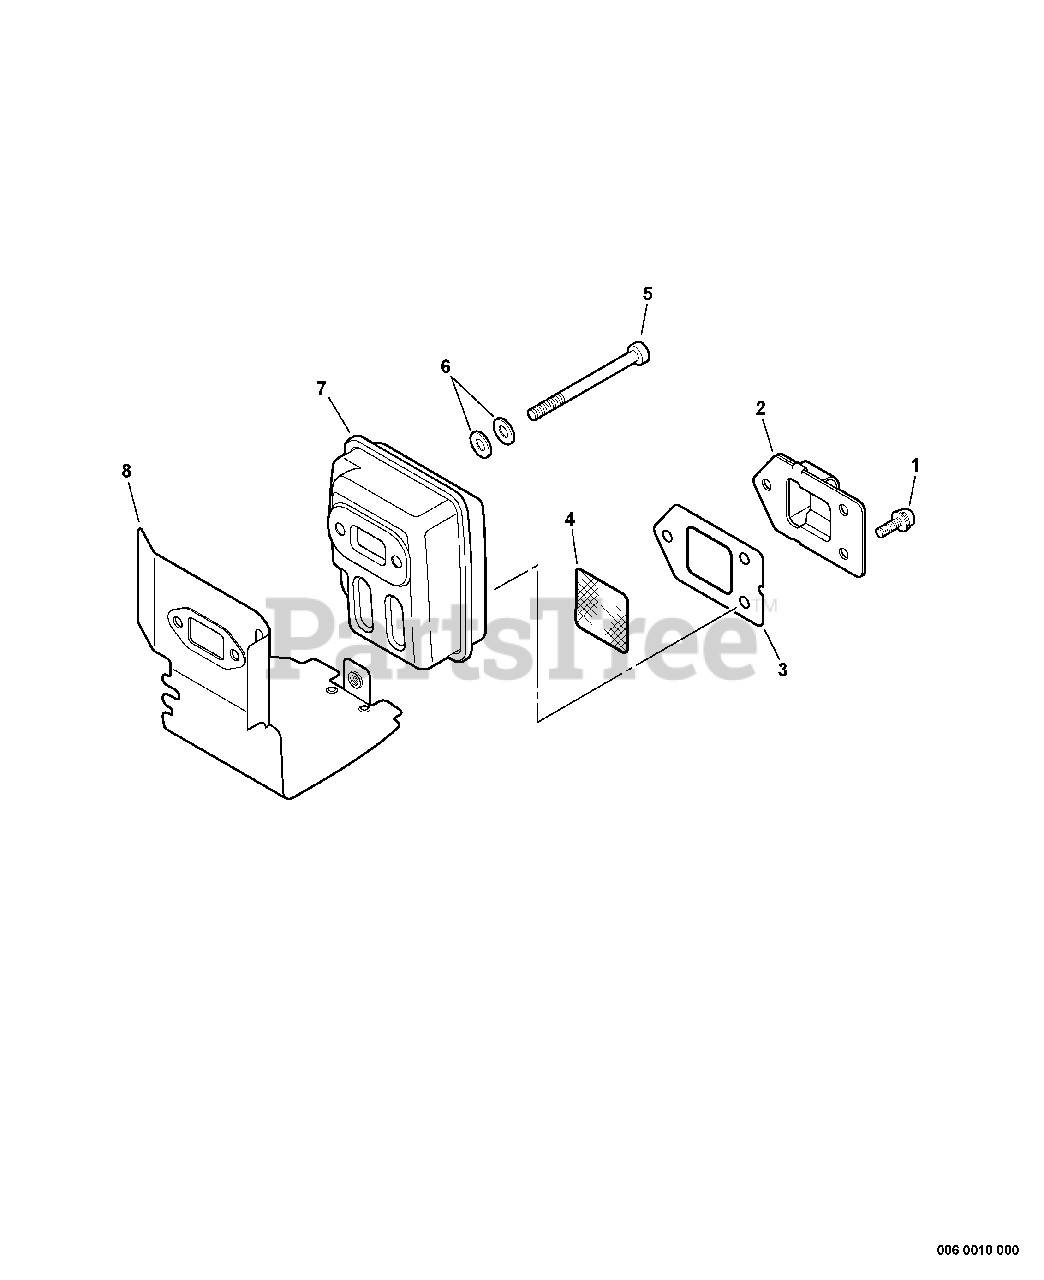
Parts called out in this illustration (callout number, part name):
1	SCREW - 4X10
2	GUIDE, EXHAUST
3	GASKET, EXHAUST
4	SCREEN, SPARK ARRESTOR
5	SCREW - 5X55
6	WASHER - 5
8	SHIELD, EXHAUST
